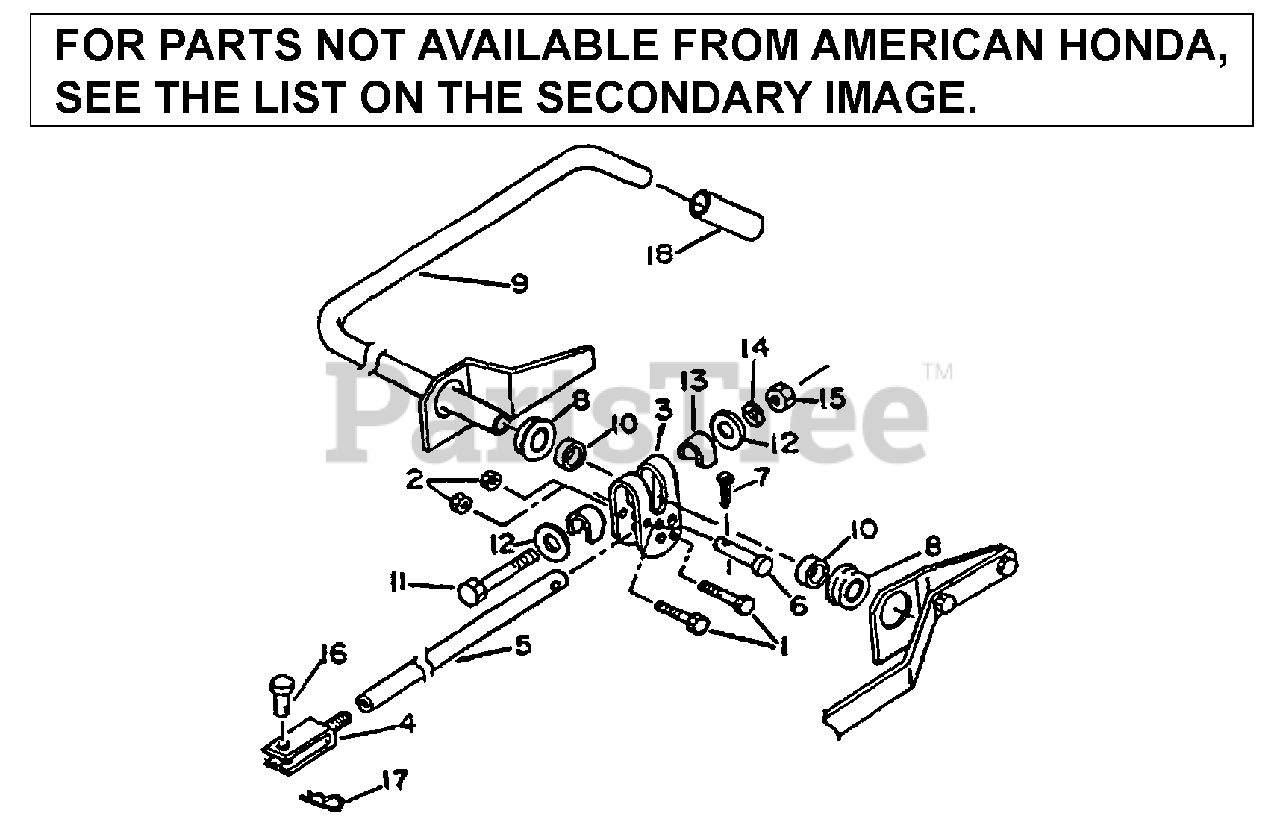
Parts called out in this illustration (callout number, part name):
3	LEVER, LIFT
4	FORK, ADJUSTMENT
5	ARM, PUSH
8	BEARING, FLANGE
9	ARM, LIFT
10	SPACER, TUBE
13	PLATE, RETAINER
16	PIN, CLEVIS
17	PIN, HAIR (3X65)
18	GRIP, RUBBER HANDLE
